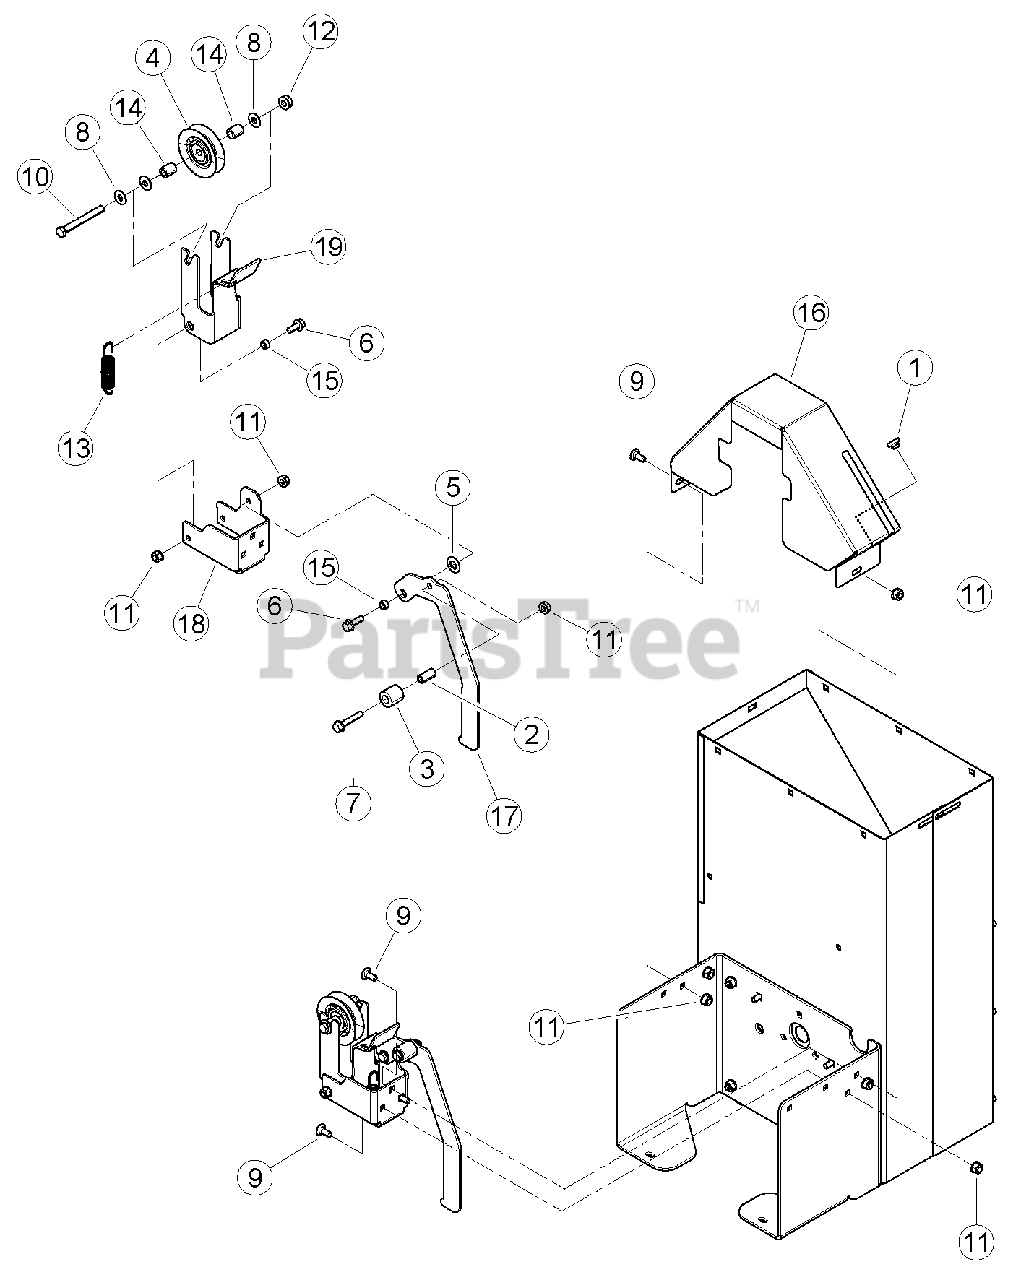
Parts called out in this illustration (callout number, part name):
1	BUMPER, RUBBER
2	SPACER, 0.5 X 1.00
3	ROLLER, 0.5 X 1.00 X 1.00 NYLON
4	IDLER, INSIDE
5	WASHER, 1/2 INCH NYLON
6	BOLT, 5/16 X 7/8 FLANGE NC
7	BOLT, 5/16 X 1-3/4 FLANGE NC
8	WASHER, 5/16" FLAT ZP
9	BOLT, 5/16 X 3/4 GR5 NC ZP CRG
10	BOLT, 3/8 X 3-1/4 HXHD GR5 ZP
11	NUT, 5/16-18 NYLOCK-FLANGE
12	NUT, 3/8-16 NYLOCK FLANGE
13	SPRING, 3/4"OD EXTENSION
14	SPACER, 3/4" LONG IDLER TUBE
15	SPACER, .50 X .25
16	SHIELD, UPPER
17	HANDLE, ENGAGEMENT
18	MOUNT, IDLER BRACKET
19	BRACKET, IDLER 3 IN CHIPPER
